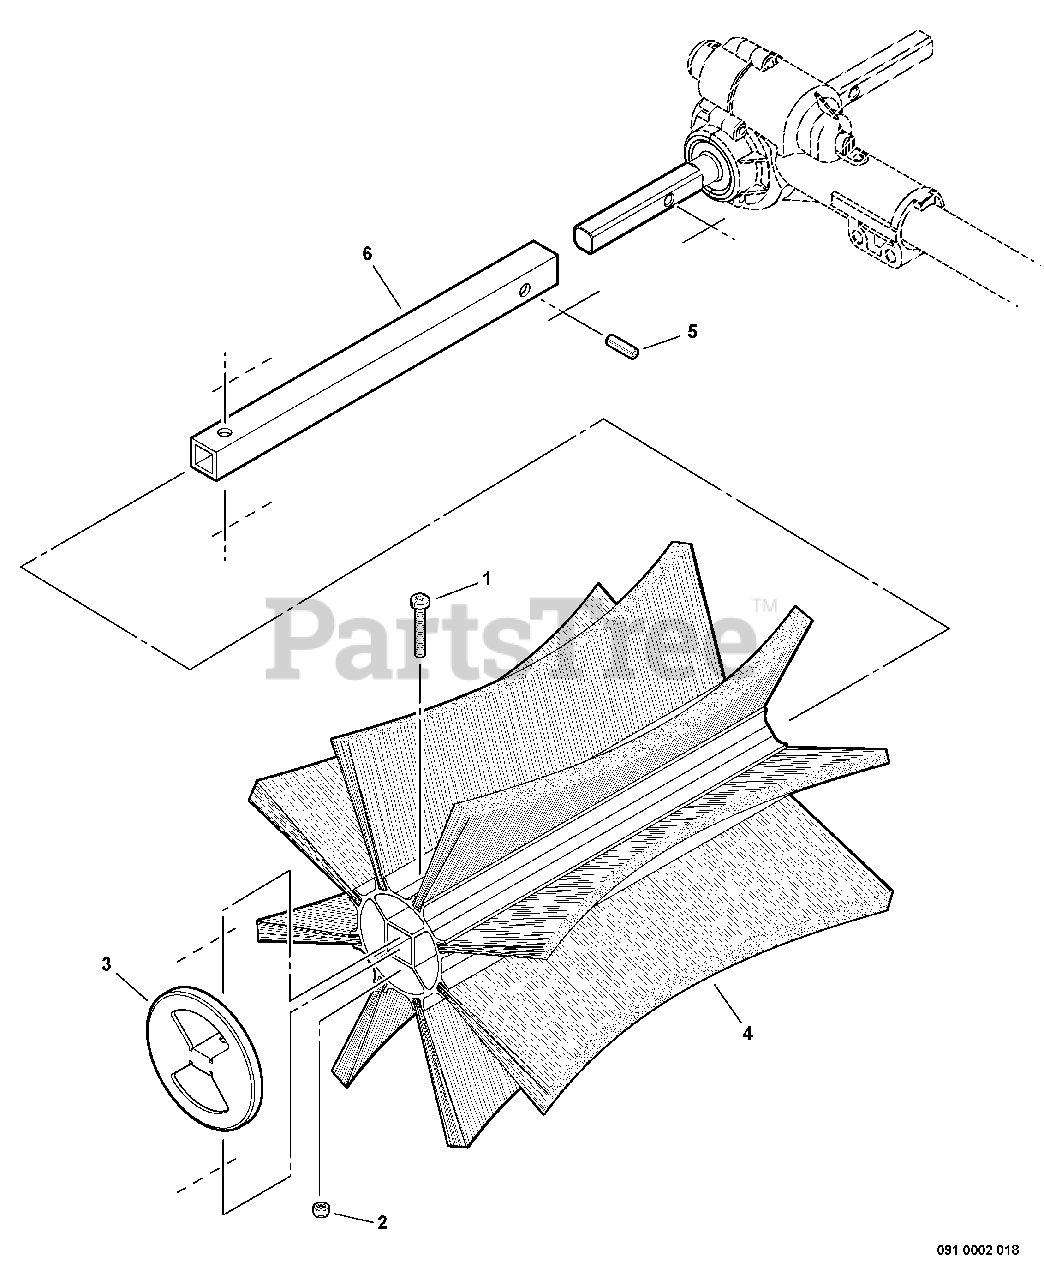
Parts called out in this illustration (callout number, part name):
1	SCREW - 5X30
2	LOCKNUT - 5
3	CAP, END
4	BRUSH ASSY - .018 INCH
5	PIN - SPRING
6	COUPLING, SHAFT
